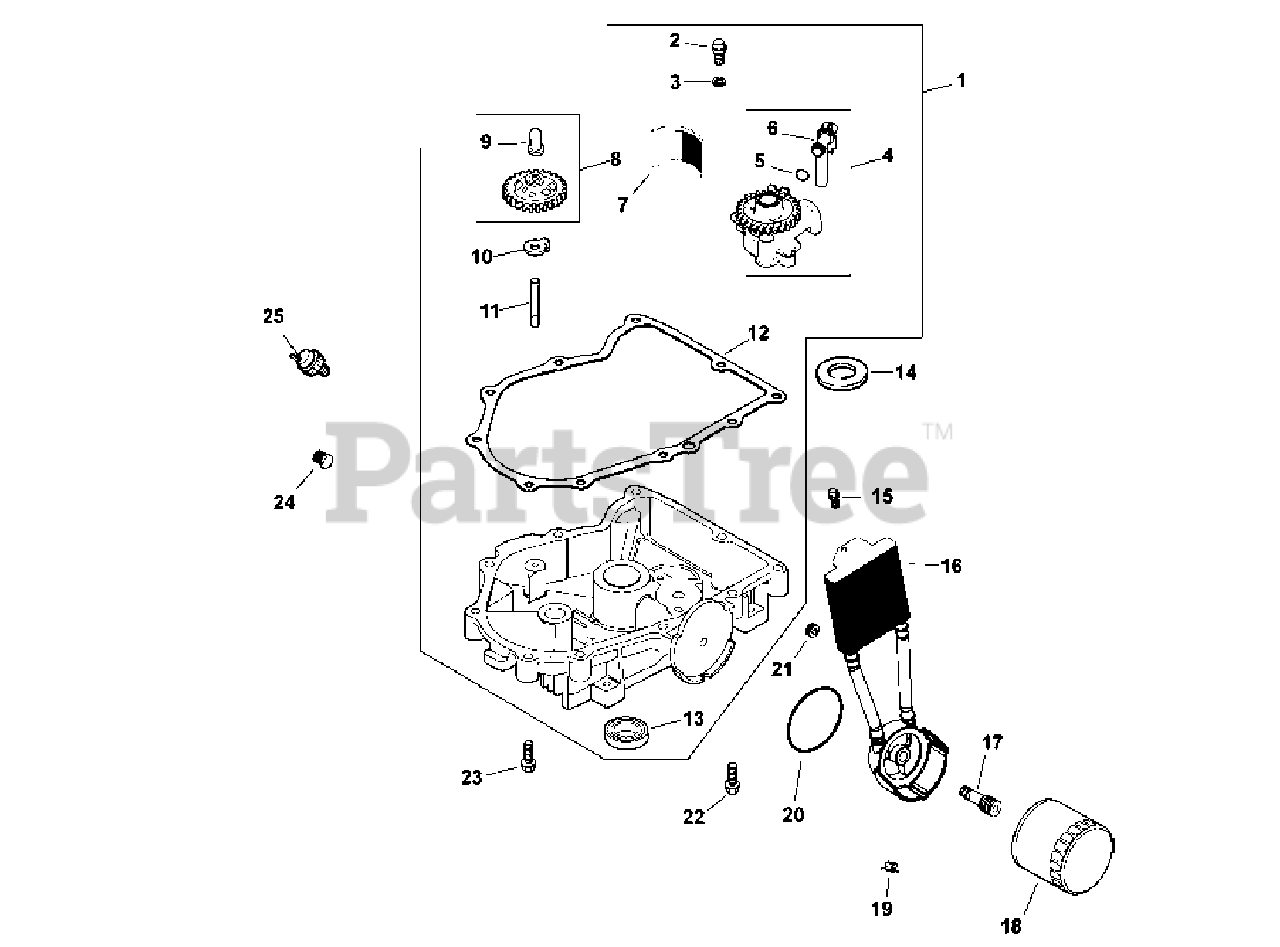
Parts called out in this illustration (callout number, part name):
1	Oil Pan Assembly Kit (Inc. 2-13)
2	Flange Screw, M6 x 1.0 x 25
3	Flat Washer, 6 mm
4	Oil Pump Assembly Kit (Inc. 5 & 6)
5	Oil Pick-Up O-Ring
6	Oil Pick-Up Tube Kit
8	Governor Gear Kit w/Pin (Inc. 9)
9	Governor Regulating Pin
11	Governor Gear Shaft
12	Oil Pan Gasket Kit (Select-A-Seal)
14	Thrust Shim (Black .686 mm)
15	Tap Screw, M6 x 1.7 x 18
16	Oil Cooler Kit (Inc. 17 & 20)
17	Oil Filter Nipple
19	Plastic Nut (Black)
20	Oil Cooler O-Ring
21	Countersink Pipe Plug, 3/8
22	Flange Screw, M8 x 1.25 x .45
23	Flange Screw, M8 x 1.25 x 45
24	Pipe Plug, 3/8
25	Oil Pressure Switch
